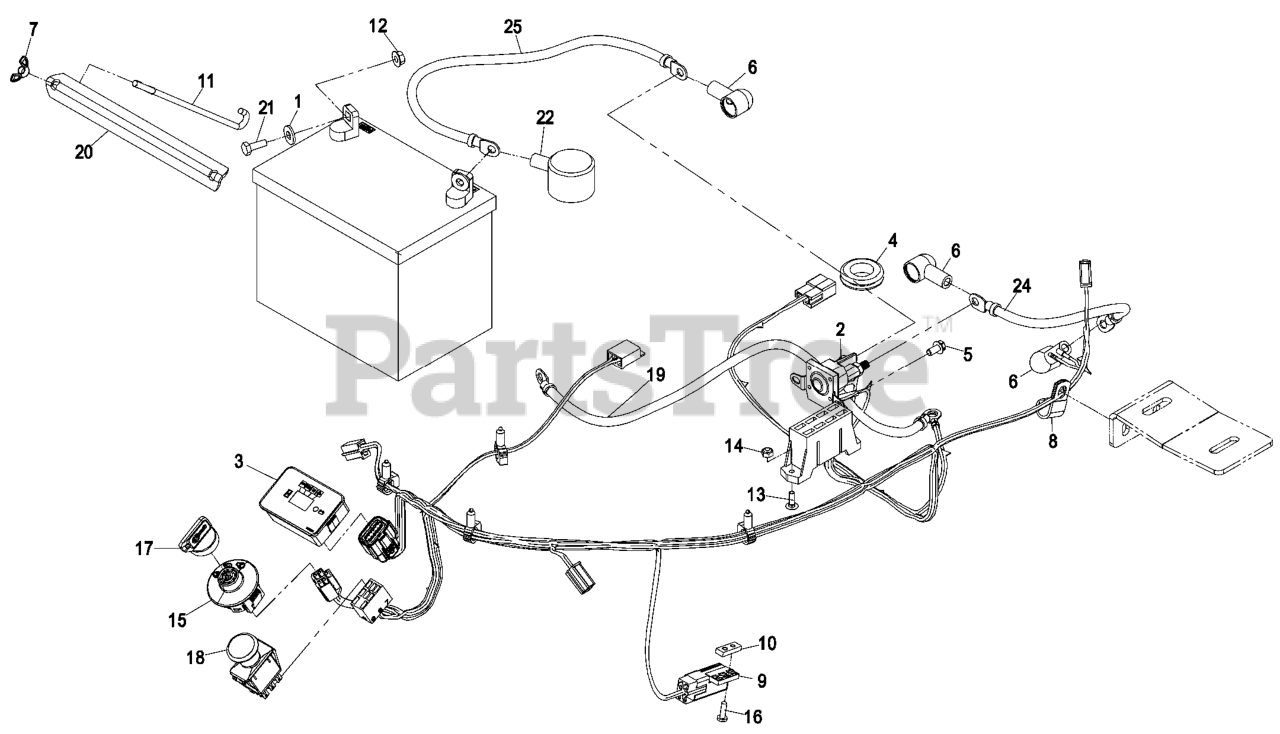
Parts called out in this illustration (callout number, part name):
1	WASHER-FLAT
4	GROMMET
5	SCREW-HWH
6	INSULATOR-SOLENOID
7	WINGNUT
8	CLIP-LOOM
10	PLATE-TAPPED
11	BOLT-HOLDDOWN
13	BOLT-CARR
14	NUT-LOCK, NI
16	SCREW-PPH
17	KEY-IGNITION
18	SWITCH-PTO
19	CABLE-BATTERY, NEGATIVE
20	ANGLE-BATTERY
21	SCREW-HH
22	INSULATOR-BATTERY
23	HARNESS-WIRE
24	POSITIVE STARTER CABLE AS
25	POSITIVE BATTERY CABLE AS
